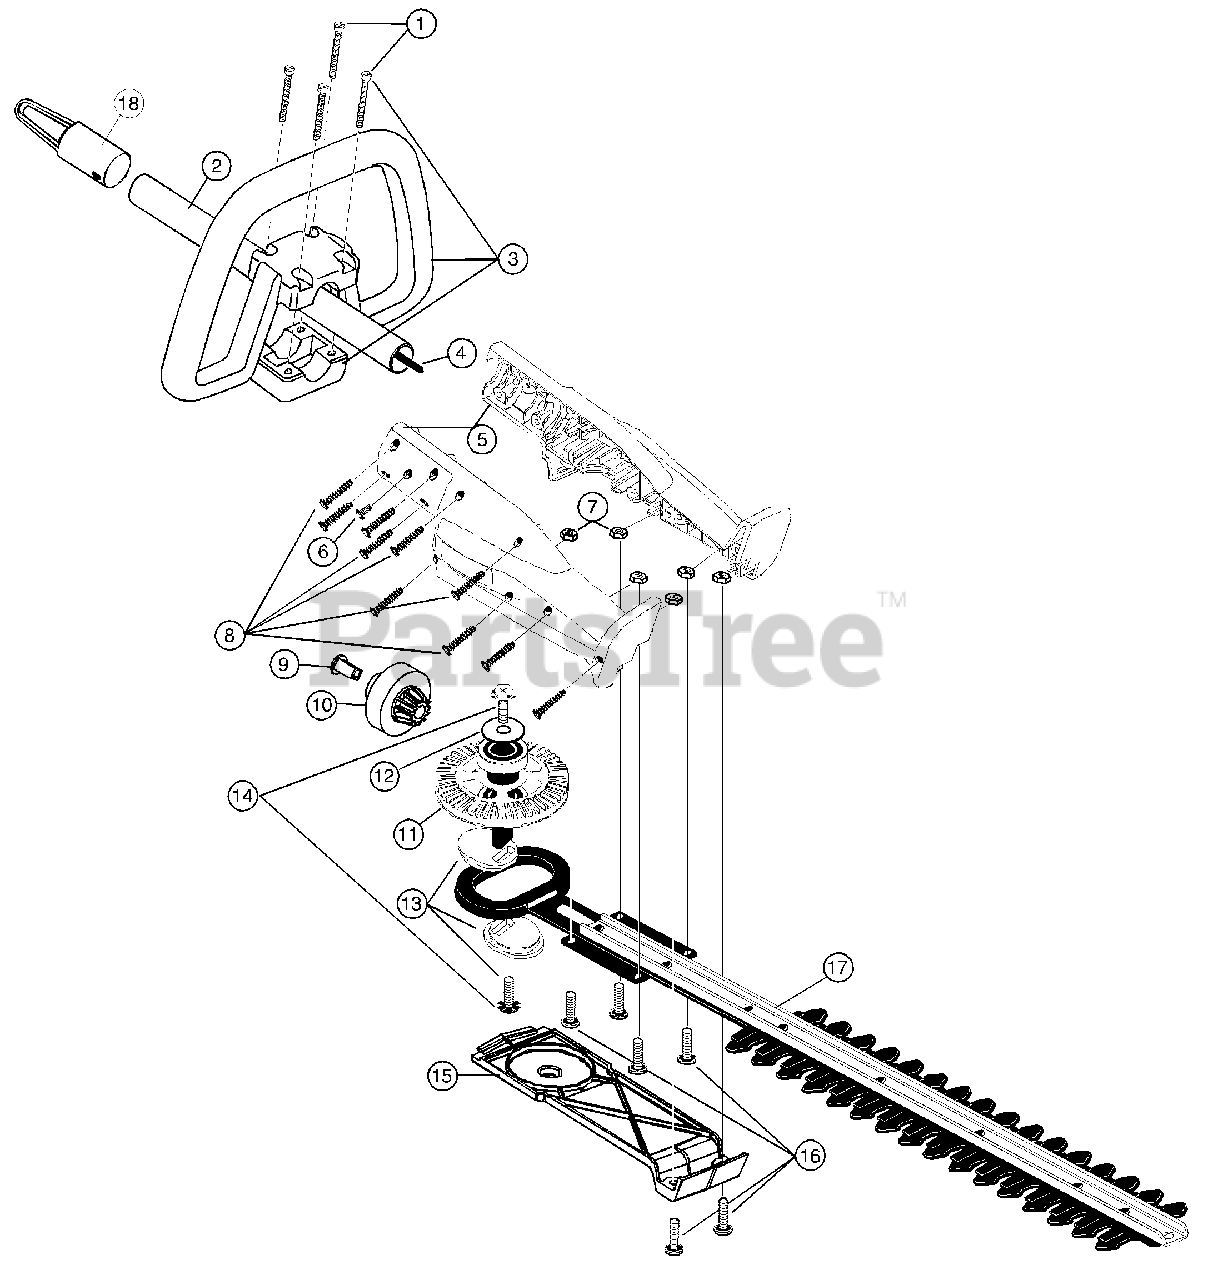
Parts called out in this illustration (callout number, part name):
2	Drive Shaft Housing Assembly
3	Loop Handle Assembly
4	Drive Shaft Assembly
5	Housing Set
6	Anti-Rotation Screw
8	Housing Screw
9	Insulator
10	Pinion Gear
11	Bevel Gear Assembly
13	Cam Assembly
15	Bottom Plate
17	Cutting Blade Assembly
18	Hanger
